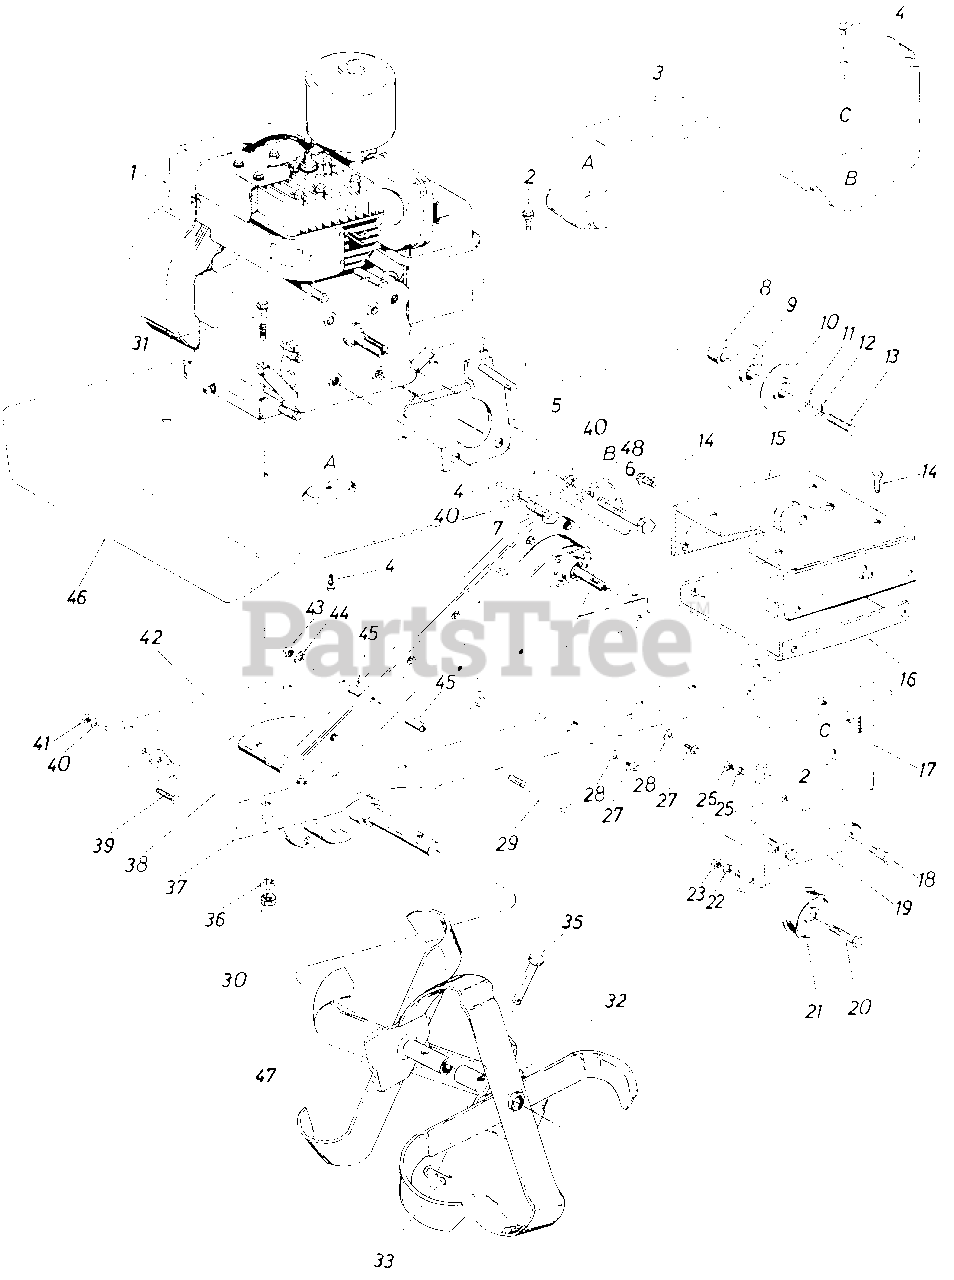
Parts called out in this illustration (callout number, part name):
1	Engine
2	Hex Wash. Hd. Self-Tap Scr. 5/16-24 x .50" Lg.
3	Belt Cover
4	Hex Wash. Hd. Self-Tap Scr. 1/4-20 x .50" Lg.
5	Belt Keeper Brkt. Ass'y.
6	Hex Bolt 5/16-24 x 2.25 Lg. (Grade 5)
7	Hex Bolt 5/16-24 x .62" Lg. (Grade 5)
8	Spacer
9	Pulley Half
10	Pulley Half
11	Fl-Wash. 3/8" I.D. x 1.25" O.D. x .100
12	L-Wash. 3/8" I.D.
13	Hex Scr. 3/8-24 x 1.00" Lg.
14	Hex Wash. Hd. Self-Tap Scr. 31/-24 x 718" Lg.
15	Handle Mounting Brkt Ass'y.
16	U-Channel Brkt. Ass'y.
17	Idler Mounting Brkt.
18	Shld. Bolt
19	Idler Brkt. Ass'y.
20	Hex Scr. 3/8-16 x 1.50" Lg.
21	Idler Pulley
22	L-Wash. 3/8" I.D.*
23	Hex Nut 3/8-16 Thd.
25	L-Wash. 3/8" I.D.*
26	Hex Nut 3/8-16 Thd.
27	Hex Wash. Hd. Self-Tap Scr. 1/4-20 x .50" Lg.
28	Belleville Wash. .26 I.D. x .75 O.D. x .060
29	Hex Scr. 5/16-18 x 2.75" Lg.
30	Hex Nut 5/16-18 Thd.*
31	Hex Bolt 5/16-18 x 1.50" Lg.
32	See Tine Chart
33	Hairpin Cotter
35	Clevis Pin
36	L-Wash. 5/16" I.D.*
37	Frame Rail-L.H.
38	Front Brace Brkt.
39	Hex Scr. 5/16-18 x .75" Lg.*
40	L-Wash. 5/16" I.D.*
41	Hex Cent. L-Nut 5/16-18 Thd.
42	Frame Rail-R.H.
43	Hex Cent. L-Nut 5/16-18 Thd.
44	L-Wash. 5/16" I.D.*
45	Spacer
46	Tine Shield
47	See Tine Chart
